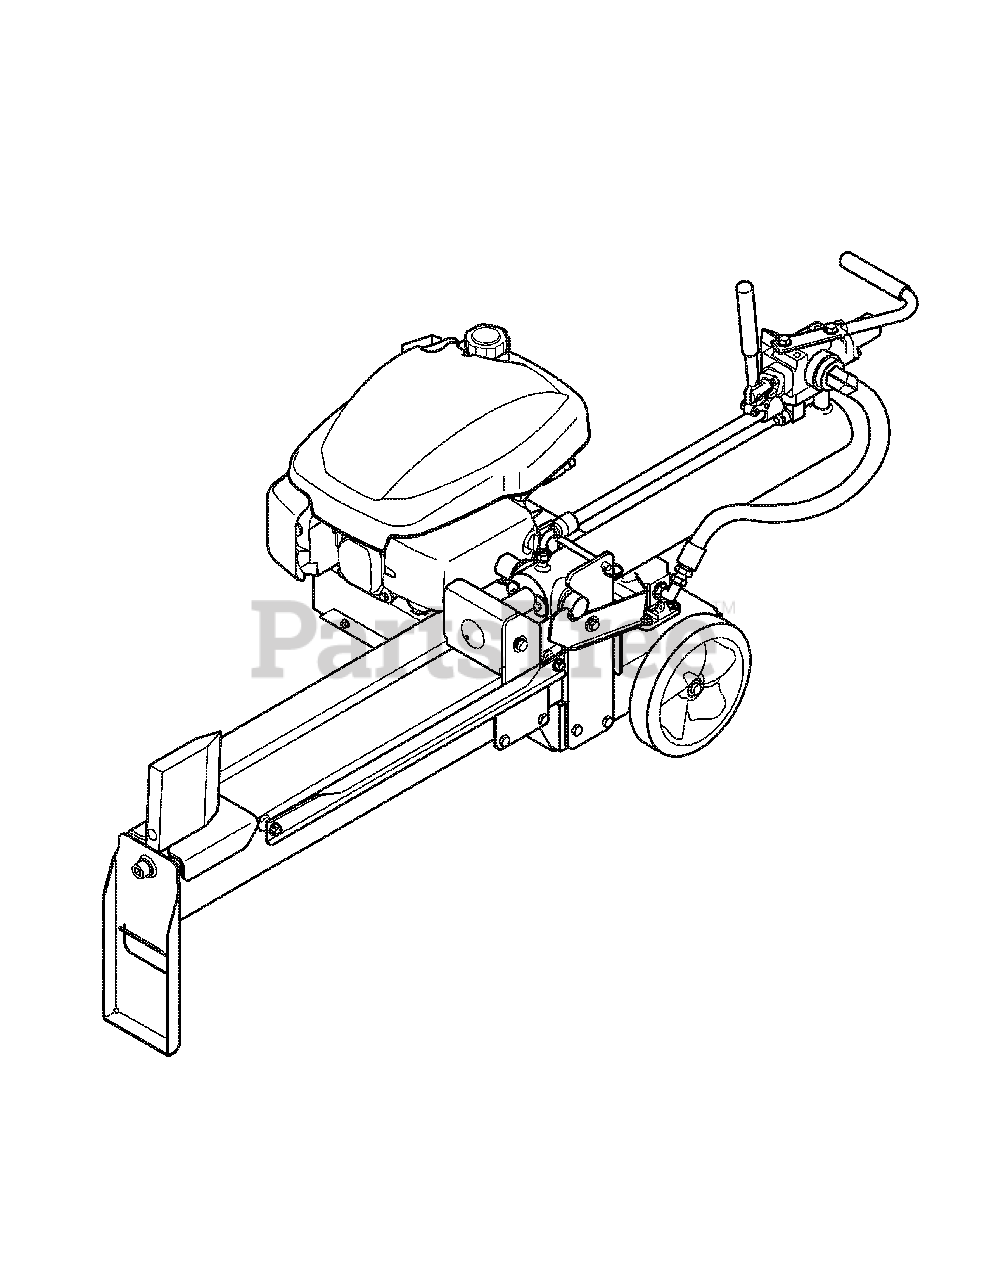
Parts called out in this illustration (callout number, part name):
NA	Hydraulic Filter
NA	Inlet Filter
NA	Vented Dipstick
NA	Flexible Coupling
NA	Adjustable Gibbs
NA	Chain
NA	Hub Cap
